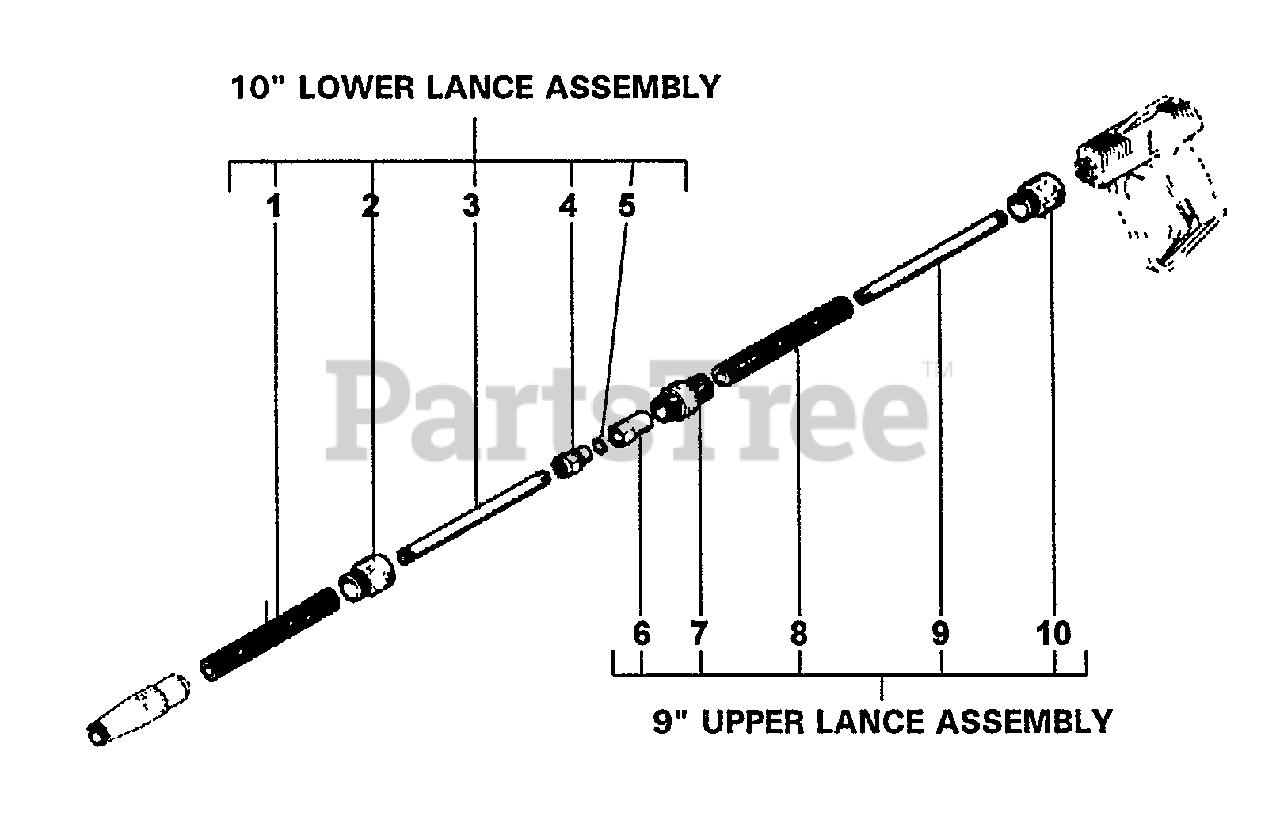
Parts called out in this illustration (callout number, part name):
1	GRIP, HANDLE
2	NUT, RING
3	PIPE
4	COUPLING, MALE
5	O-RING
6	COUPLING, FEMALE
7	CONNECTOR
8	PROTECTOR, LANCE, FIX-UP
9	PIPE
10	CONNECTOR
